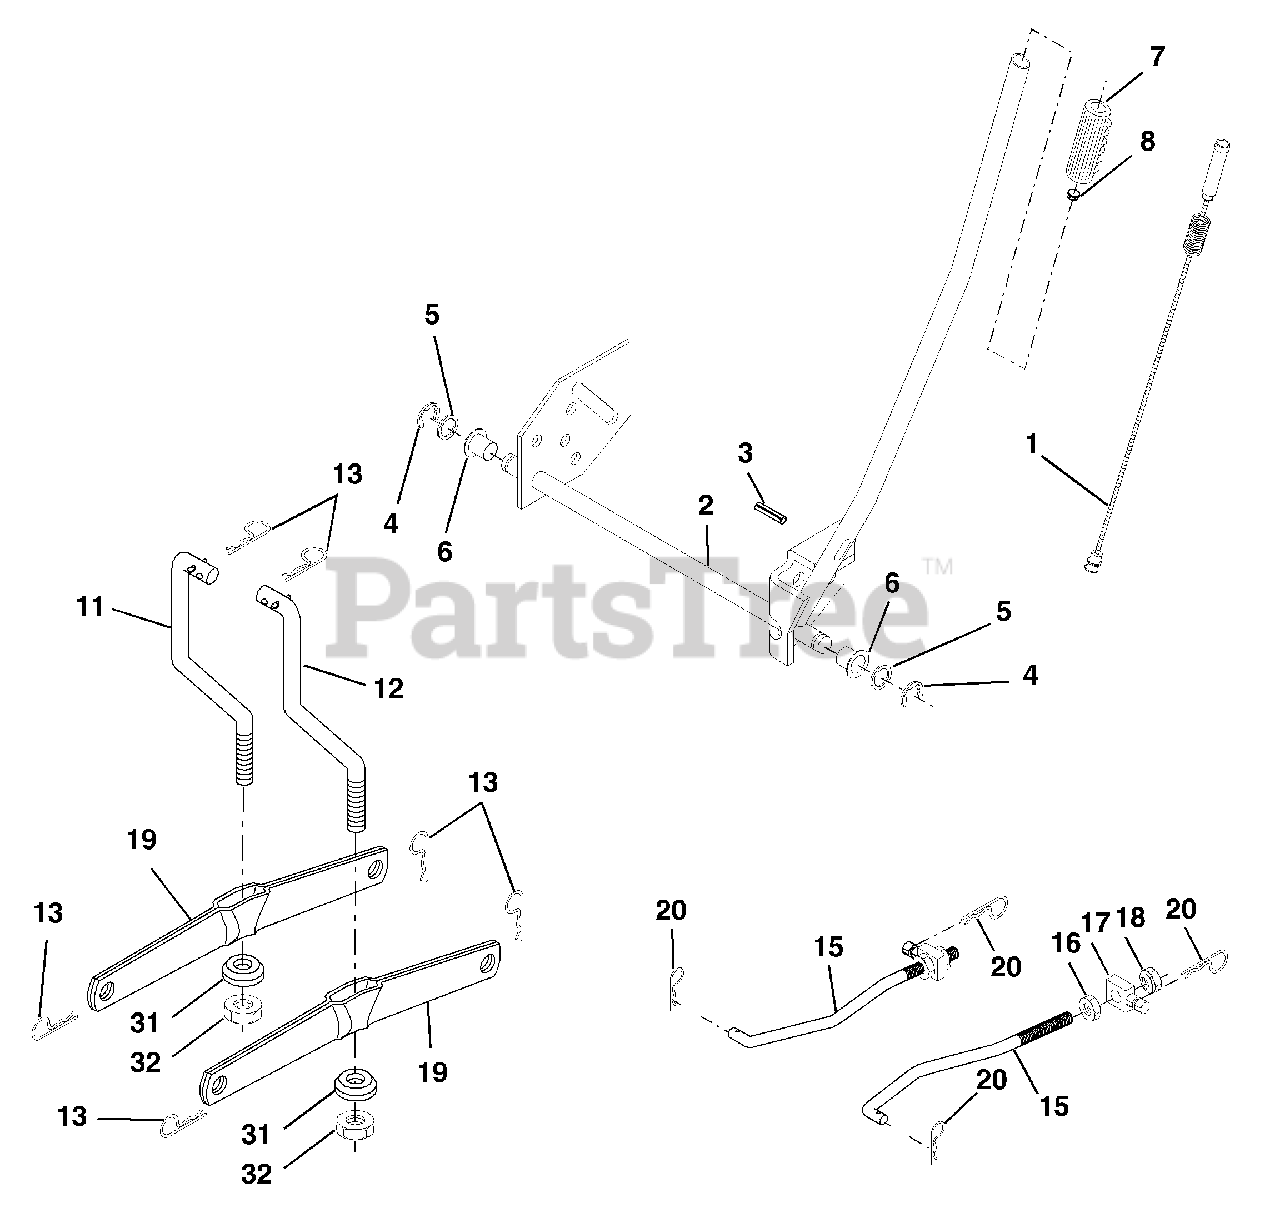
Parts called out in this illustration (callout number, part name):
1	Wire Asm Inner W/plunger LT
2	Shaft Asm Lift
3	Pin Groove
4	E Ring #5133-62
5	Washer PLTD 21/32 X 1 X 21 ga
6	Bearing Nylon Blk 629 Id
7	Grip Handle Bicycle
8	Button Plunger Black
11	Link Lift LH
12	Link Lift RH
13	Retainer Spring
15	Link Front
16	Nut Jam Hex 1/2-13 Unc
18	Nut Lock W/Wsh 1/2-13 Unc
19	Arm Suspension Rear
20	Spring, Retainer
31	Bearing Pvt. Lift
32	Nut Crownlock 3/8-24
